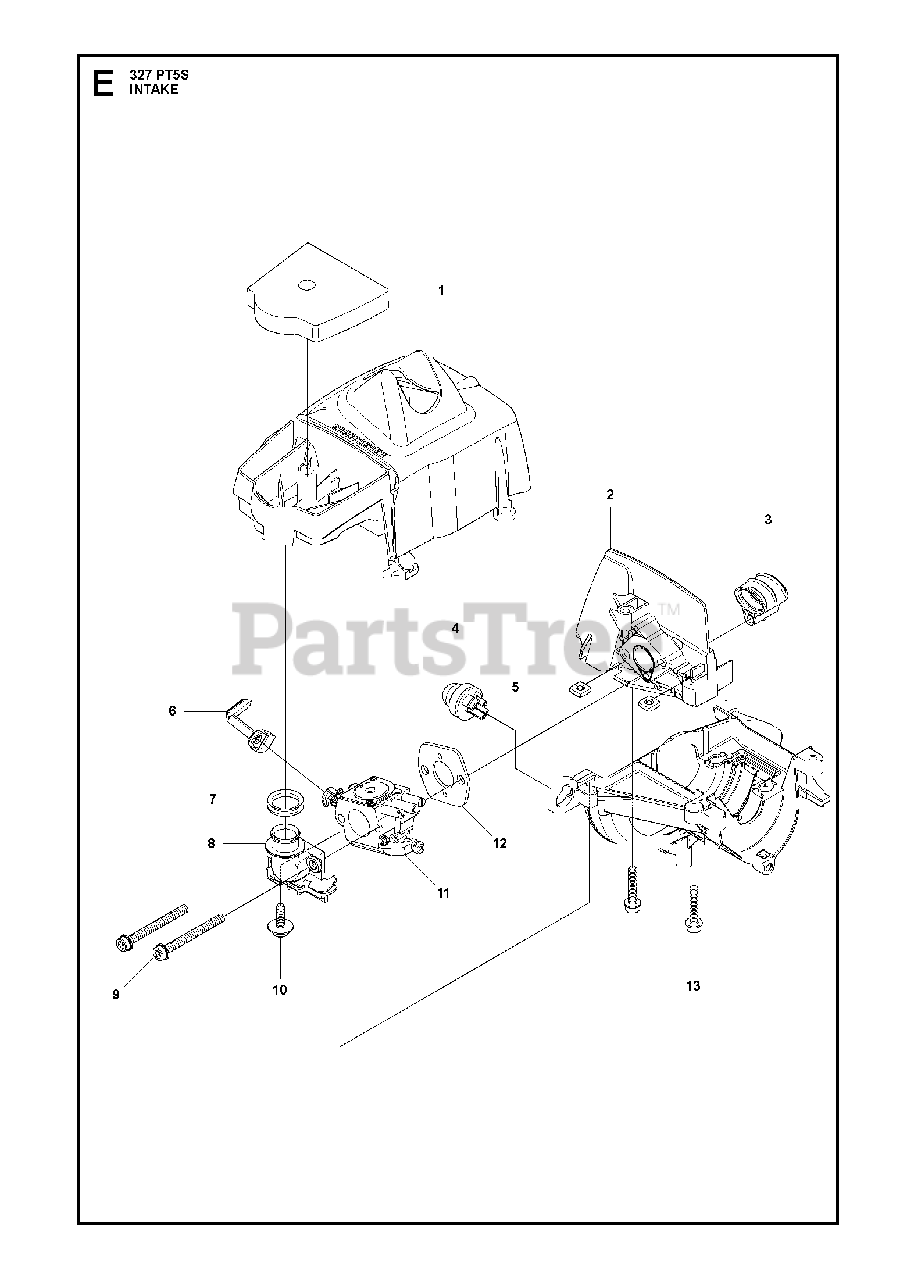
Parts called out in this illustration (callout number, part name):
1	AIR FILTER
4	AIR PURGE BUBBLE
6	CHOKE CONTROL
11	CARBURETOR
